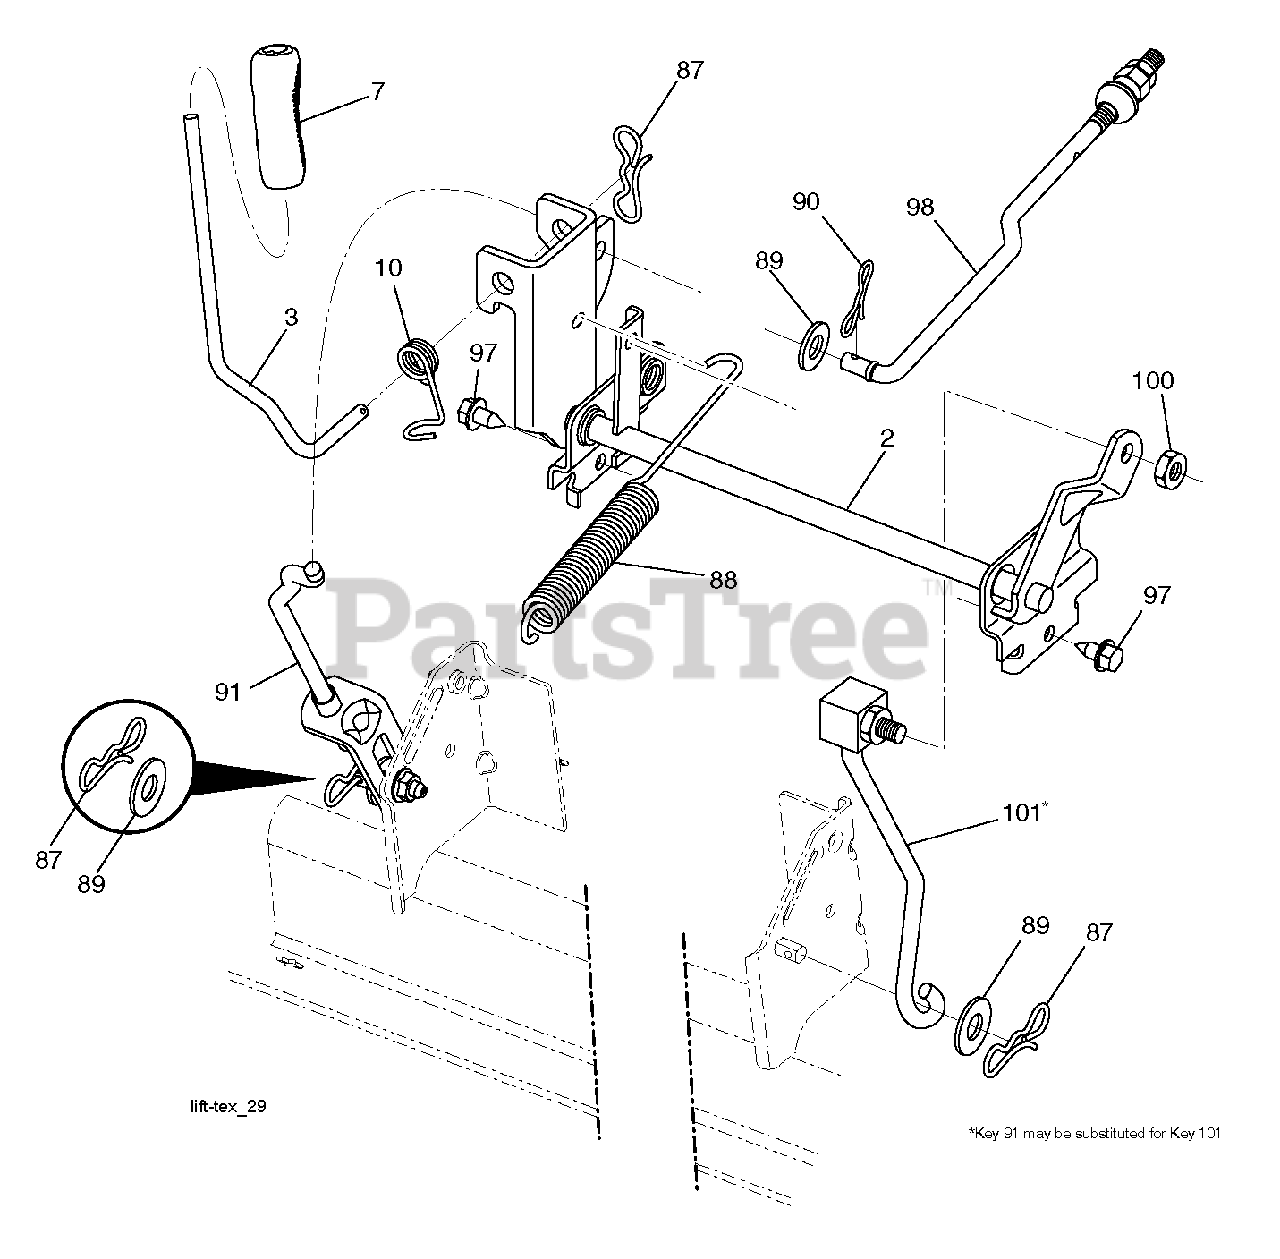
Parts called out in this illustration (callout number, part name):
2	SHAFT.ASM.CROSS.LIFT
3	LEVER.LIFT.HANDLE.LT
7	GRIP.HANDLE.LIFT.PVC.BLACK
10	SPRING.TORSION.LIFT.HANDLE
87	PIN.COTTER.7/16.BOW TI.
88	SPRING.LIFT.ASSIST
89	WASHER.CLEAR.ZINC
90	PIN.COTTER.5/16.BOW TI
91	LINK.ASM.LIFT.REAR
97	SCREW, 3/8-16X3/4
98	LINK.ASM.SUSP.FRONT.MW
100	LOCKNUT
101	LINK.ASM.LIFT.FIXE.38/42/46"
